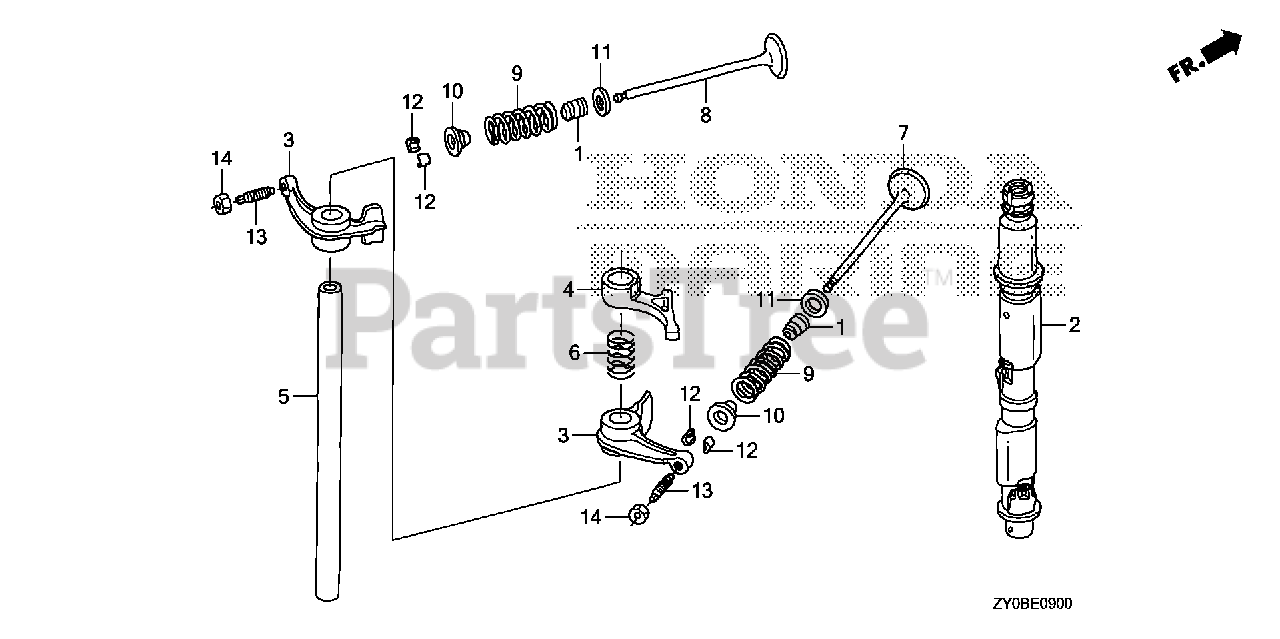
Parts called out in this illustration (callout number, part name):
1	SEAL, VALVE STEM (ARAI)
3	ARM, VALVE ROCKER
4	ARM, FUEL PUMP ROCKER
5	SHAFT, ROCKER ARM
6	SPRING, ROCKER ARM
7	VALVE, IN.
8	VALVE, EX.
9	SPRING, VALVE
10	RETAINER, VALVE SPRING
11	SEAT, VALVE SPRING
12	COTTER, VALVE
13	SCREW, TAPPET ADJ.
14	NUT, TAPPET ADJ.
